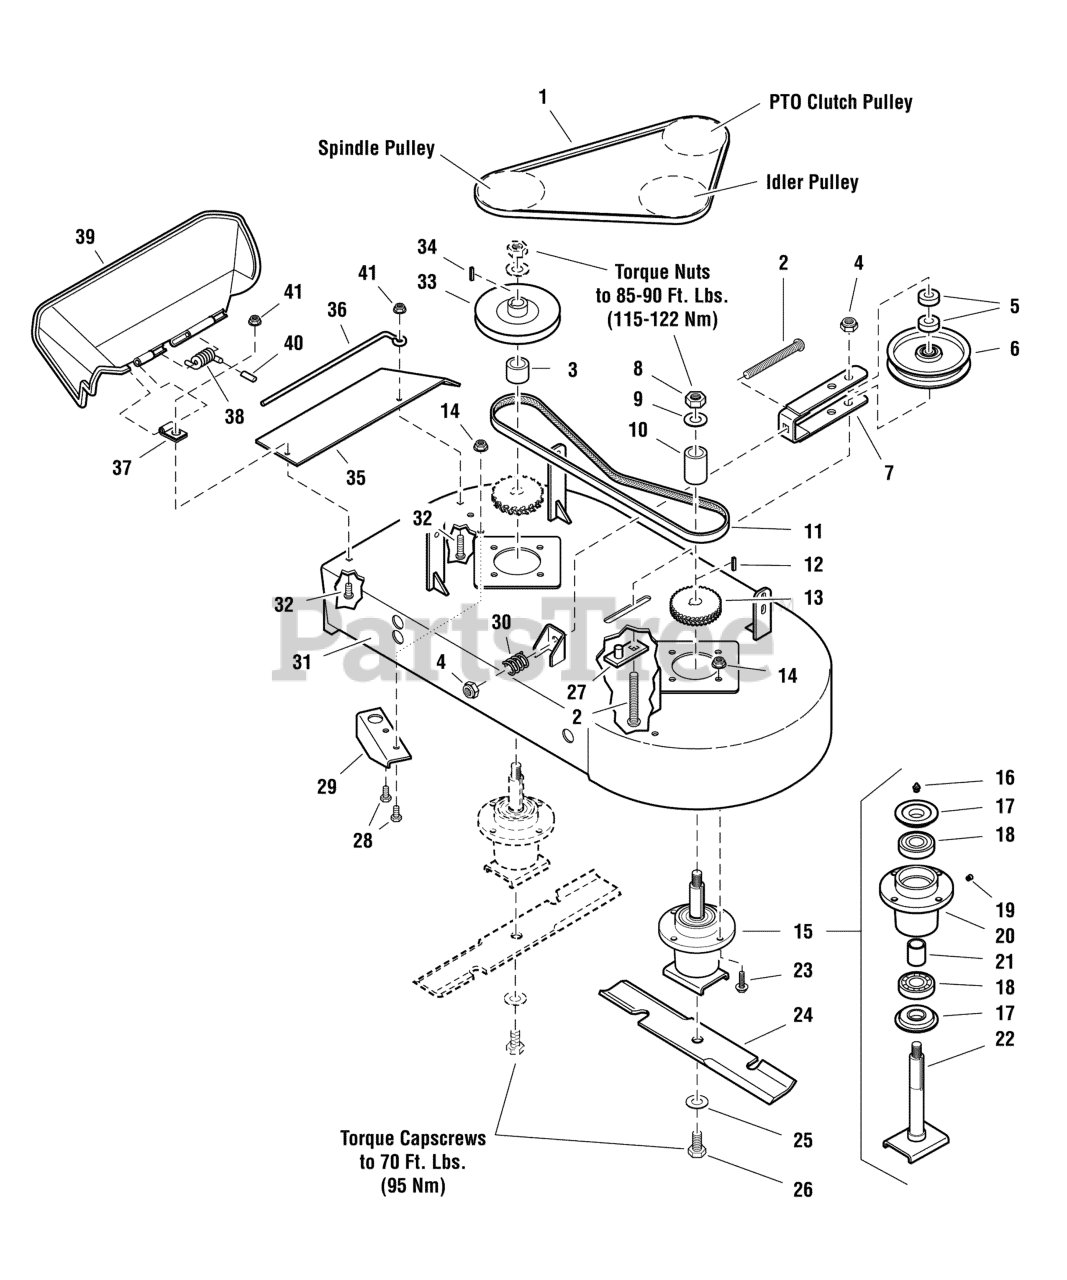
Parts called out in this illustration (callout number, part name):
1	BELT,#7-8390, 52
2	BOLT, 1/2-13 X 4", CARRIAGE
3	SPACER, 1.00 X 1.50 X 1.19
4	NUT, Hex Flange, Nylock, 1/2-13
5	SPACER, .52 X 1.00 X .44
6	PULLEY, FLAT IDLER, 5.0X.75
7	WELD, IDLER PULLER
8	NUT, 3/4-16 HEX
9	WASHER, 3/4 BELLEVILLE
10	SPACER, 1.00 X 1.57 X 2.19
11	BELT, SPROCKET DRIVE
12	KEY, 1/4" SQ. X 3/4
13	SPROCKET, GOODYEAR EAGLE PD
14	NUT, 5/16-18 HEX NYLOCK FLANGE
15	ASSM, SPINDLE, BLADE SADDLE
16	GREASE FITTING
17	TRASH SHIELD
18	BEARING
19	RELIEF VALVE
20	SPINDLE HOUSING
21	SPACER, 1.00 X 1.25 X 1.75
22	SPINDLE SHAFT w/ SADDLE
23	BOLT, 5/16-18 X 1 1/4" FLANGE
24	BLADE, 18
25	WASHER, 5/8" USS
26	BOLT, 5/8-11 X 1-3/4 GD8
27	WELD, RETAINER PULLEY
28	BOLT, 5/16-18 X 3/4", CARRIAGE
29	PLATE, BAFFLE
30	SPRING, COMPRESSION 2" MEDIUM
31	DECK SHELL W/DECALS, 36 HYDROCUT
32	BOLT, 1/4-20 X 1", CARRIAGE
33	PULLEY, SPINDLE
34	KEY, 1/4 SQ X 1
35	PLATE, CHUTE SUPPORT
36	WELD, MOUNT, DISCHARGE CHUTE
37	CLAMP, WIRE, .312DIA . (1) .281 HOLE BLK
38	SPRING, TORSION
39	DEFLECTOR, BLACK
40	CAP, VINYL
41	NUT, 1/4-20 HEX NYLON LOCK
